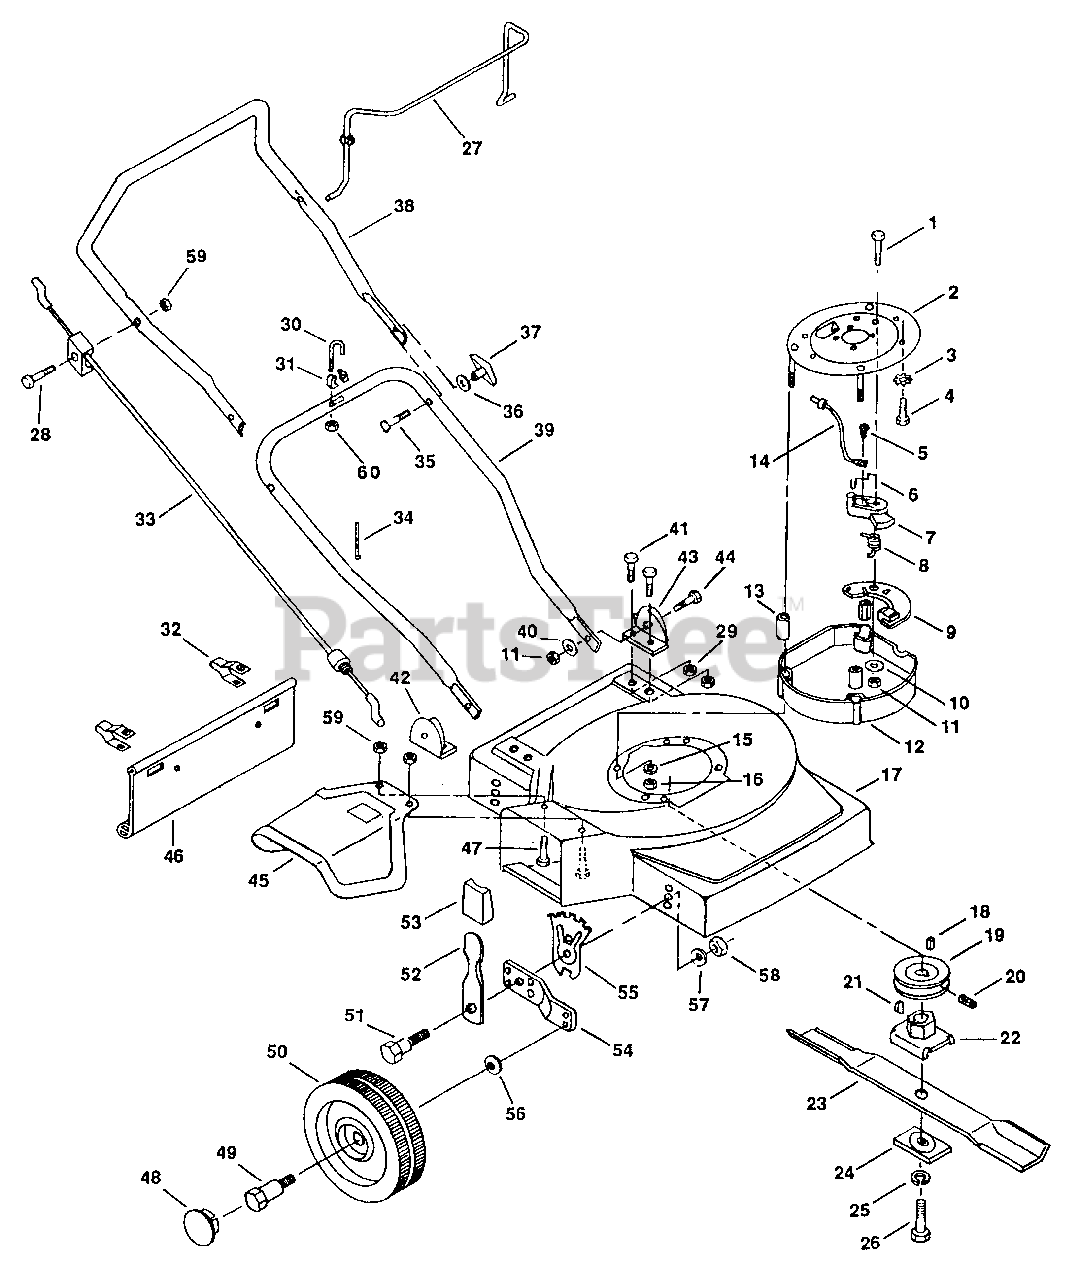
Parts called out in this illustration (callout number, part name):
1	Hex Bolt 3/8-16 x 1-3/4" Lg.
2	Plate Assembly
3	Int. L-Wash. 1/4" I.D.
4	Hex Bolt 1/4-20 x 5/8" Lg.
5	Screw #6-20 x 3/8 Tapping
6	Contact-Brake Arm
7	Housing-Brake Spring
8	Spring-Brake Arm
9	Brake Arm & Pad Assembly
10	Fl-Wash. 3/8" I.D.
11	L-Nut 3/8-16 Thd.
12	Spacer Ring
14	Wire Assembly-Brake Arm
15	Fl-Wash. 5/16" I.D.
16	L-Nut 5/16-18 Thd.
17	Deck Assembly-16" Steel
18	Key-Square 5/32 x 1/2"
19	Pulley-Brake
20	Set Screw 5/16-18 x 3/8"
21	Key-Woodruff #6
22	Adapter Blade Mtg.
23	Blade-16" Gas
24	Plate-Blade Retainer
25	L-Wash. 3/8" I.D.
26	Blade Bolt
27	Control-Handle
28	Hex Bolt 1/4-20 x 1-1/4" Lg.
29	L-Nut 1/4-20 Thd.
30	J-Bolt
31	Rope Guide Half
32	Clip-Trail Shield
33	Control Cable-Brake
34	Plastic Tie
35	Saddle Bolt 5/16-18 x 2
36	Saddle Washer
37	Knob Assembly
38	Upper Handle
39	Lower Handle
40	Fl-Wash. 3/8" I.D.
41	Hex Bolt 1/4-20 x 1/2" Lg.
42	R.H. Handle Bracket
43	L.H. Handle Bracket
44	Hex Bolt 3/8-16 x 3/4" Lg.
45	Safety Chute Guard
46	Safety Trail Shield
47	Carriage Bolt 1/4-20 x 3/4"
48	Hub Cap
49	Wheel Bolt
50	Front Wheel-6"
51	Pivot Bolt-Adjuster
52	Lever-Adjuster
53	Knob-Adjuster Lever
55	Plate-Height Adjuster
56	Bell-Wash. 3/8" I.D. x 7/8" O.D.
57	Bell-Wash. 3/8" I.D. x 1.13" O.D.
58	Hex Nut 3/8-16 Thd.
59	Flange Lock Nut 1/4-20
60	Keps Nut 1/4-20
